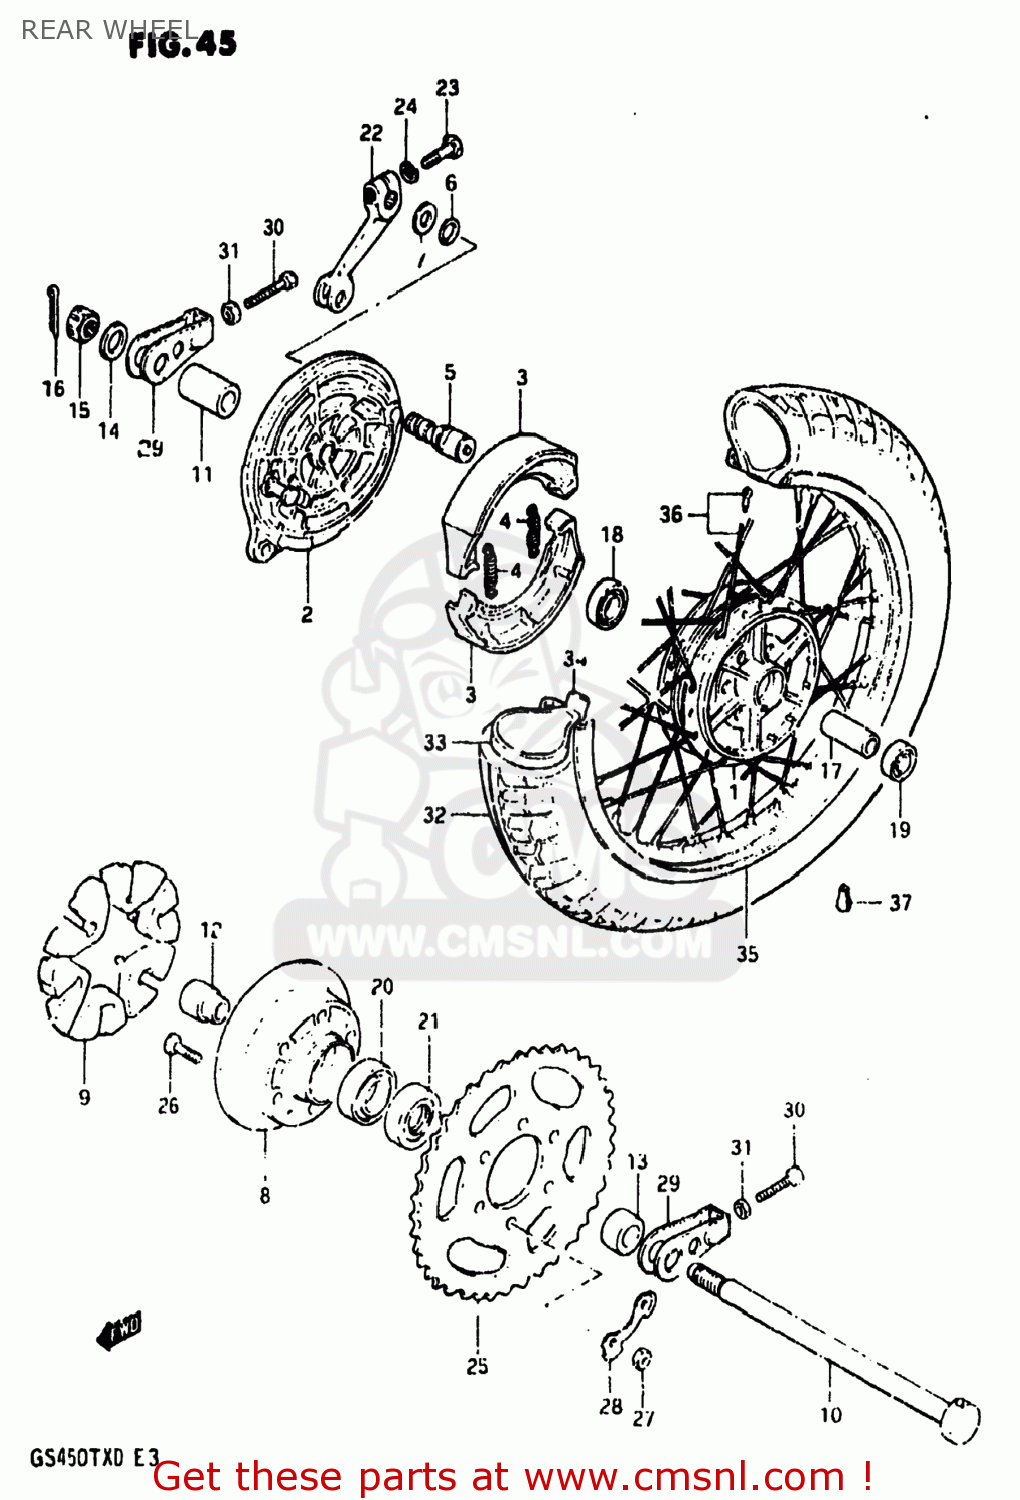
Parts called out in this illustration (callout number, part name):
1	DRUM,REAR HUB
2	PANEL,REAR HUB
3	SHOE,BRAKE
4	SPRING,BRAKE SHOE
5	CAM,FRONT BRAKE
6	O-RING,BOSS
7	WASHER (15X24X1.6)
8	DRUM,REAR SPROCKET MOUNT
9	ABSORBER,RR HUB SHOCK
10	AXLE,REAR
11	SPACER(17.5X28X44.8)
12	SPACER,REAR HUB BEARING
13	SPACER(17X30.5X22.3)
14	WASHER (17X30X3.2)
15	NUT
16	PIN,COTTER
17	SPACER (17.6X24X57)
18	BEARING
19	BEARING
20	BEARING
21	SEAL,OIL(30.5X52X8)
22	LEVER,RR BRAKE CAM
23	BOLT
24	LOCK WASHER
25	SPROCKET,REAR (NT:43)
26	BOLT
27	NUT
28	WASHER
29	ADJUSTER,CHAIN
30	BOLT 8X50
31	NUT
32	TIRE
33	TUBE ASSEMBLY,WHEEL,INNER
34	PROTECTOR,WHEEL,INNER
35	RIM,REAR WHEEL
36	SPOKE ASSY,RR
37	BALANCER,WHEEL (B)
